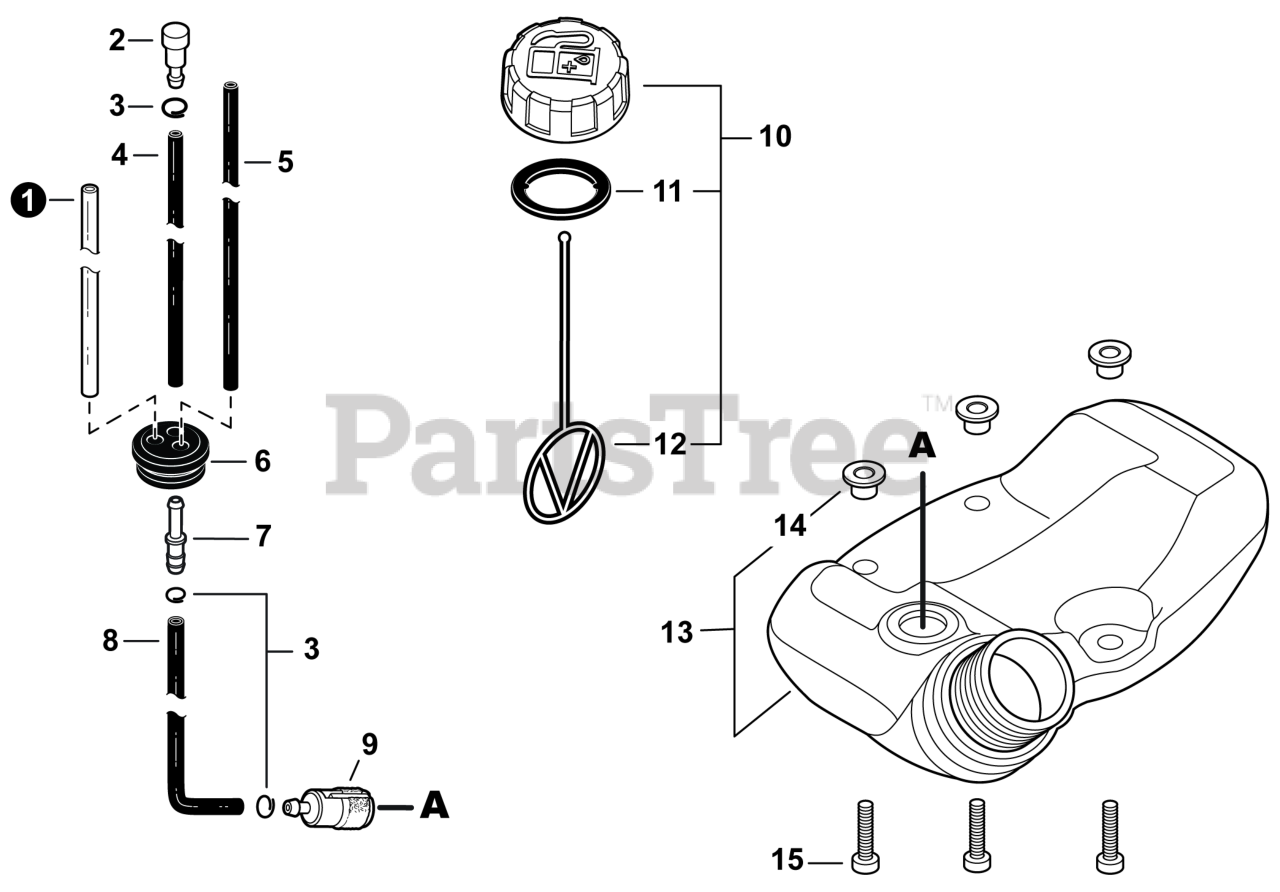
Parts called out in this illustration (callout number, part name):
1	PIPE, FUEL 3x6x80 YELLOW
2	VENT ASSY
4	PIPE, FUEL 3x5x90 BLACK
5	PIPE, FUEL 3x5.5x74 BLACK
6	GROMMET, FUEL 5
7	CONNECTOR, PIPE 5x3.5
8	PIPE, FUEL 3x5x130 BLACK
9	FILTER, FUEL
10	CAP ASSY, FUEL
11	GASKET, FUEL CAP
12	CONNECTOR, CAP L= 123
13	TANK ASSY, FUEL
14	COLLAR 5
15	BOLT, TORX 5x20
